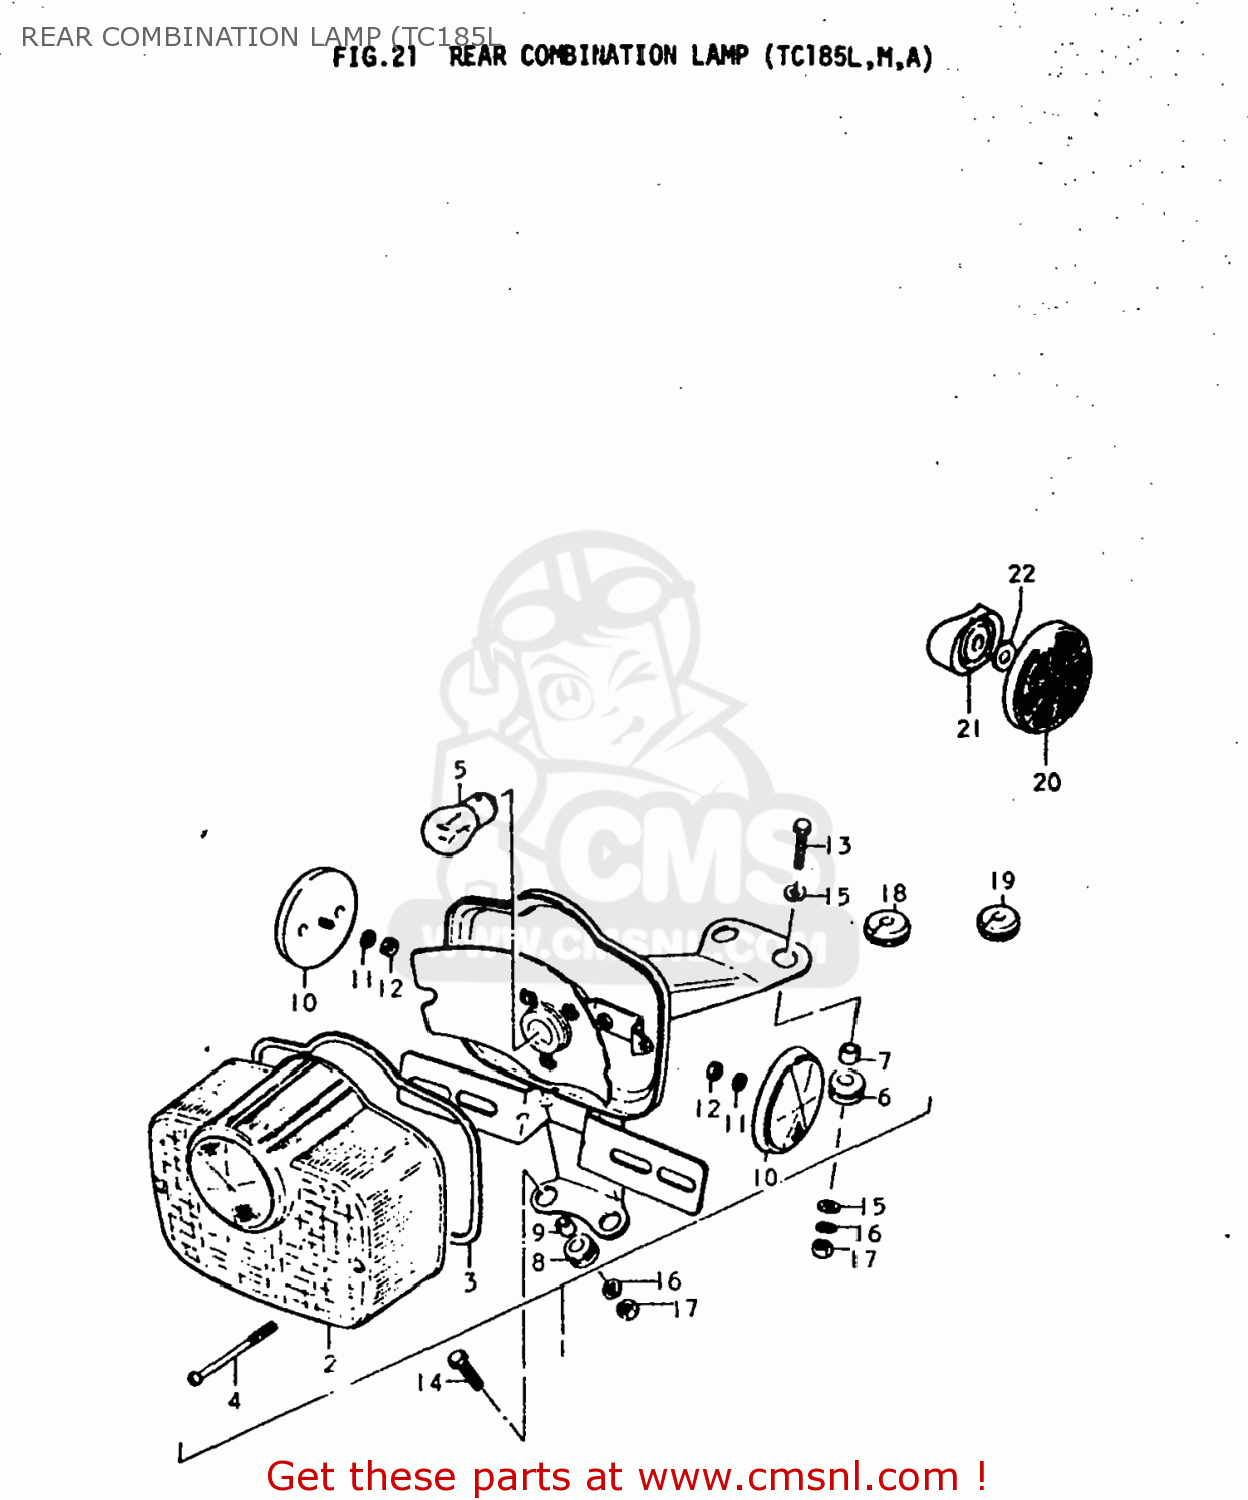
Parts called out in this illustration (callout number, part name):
1	LAMP ASSEMBLY,REAR COMBINATION
2	LENS,REAR COMBINATION LAMP
3	GASKET (NAS)
4	SCREW
5	BULB(12V23W)
6	CUSHION
7	SPACER,REAR COMBINATION LAMP
8	CUSHION
9	SPACER,REAR COMBINATION LAMP
10	REFLECTOR,REFLEX
11	LOCK WASHER
12	NUT
13	BOLT
14	BOLT
15	WASHER (6.5X20X1.2)
16	LOCK WASHER
17	NUT
18	GROMMET
19	GROMMET
20	REFLEX REFLECTOR ASSEMBLY
21	SPACER
22	WASHER (6.5X20X1.2)
